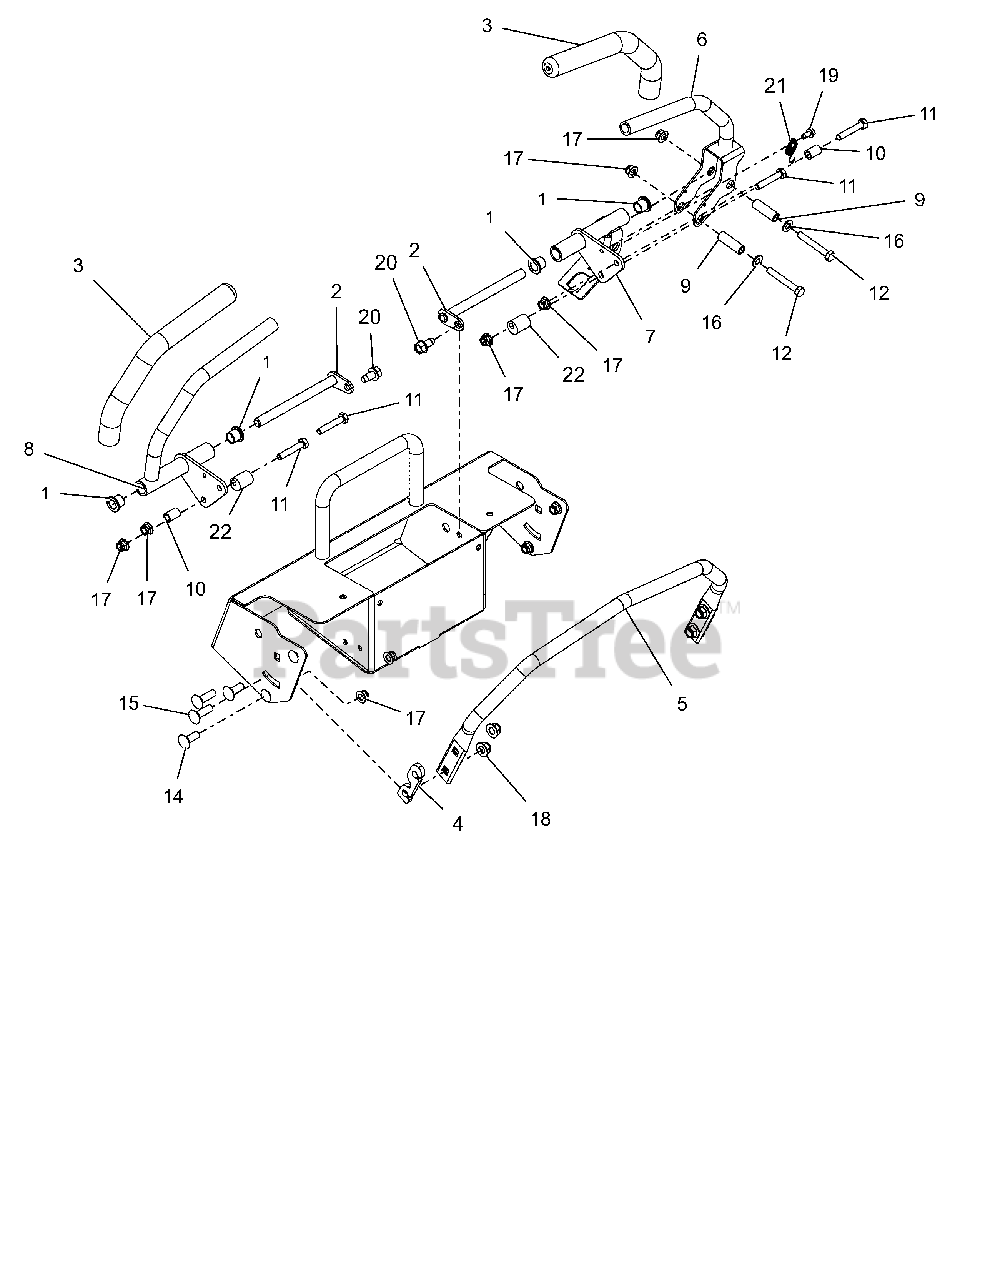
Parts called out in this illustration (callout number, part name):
1	BRG, FLG .500X.620X.500 BRNZ
2	WLDT, PIN AND LOCK Y
3	GRIP, HANDLEBAR
4	SHIM, 5 DEG SPEED BAR
5	BAR, FORWARD STOP PRO-STANCE
6	WMT, CONTROL ARM OPC
7	WMT, CONTROL ARM (LH)
8	WMT, CONTROL ARM (RH)
9	BSHG-SLV .325X.49X1.56
10	BSHG-SLV .328X.50X.75
11	@BLT-HEX .31-18X1.75 GR5 YWZC
12	@BLT-HEX .31-18X2.25 GR5 YWZC
14	@BLT-RDHDSQNK .38-16X1.00 G5YZ
15	@BLT-RDHDSQNK .38-16X1.25 G5YZ
16	@WSHR-FL-STL.344X.688X.065YWZC
17	@NUT-LK-NYL-FLG .31-18 YWZC
18	@NUT-LK-NYL-FLG .38-16 YWZC
19	SCR-TAP .25-20X.50 HWH TR YWZ
20	@SCR-TAP .38-16X.75 HWH TR YWZ
21	SPRING, EXT. .043X.438X1.64
22	ECCENTRIC
